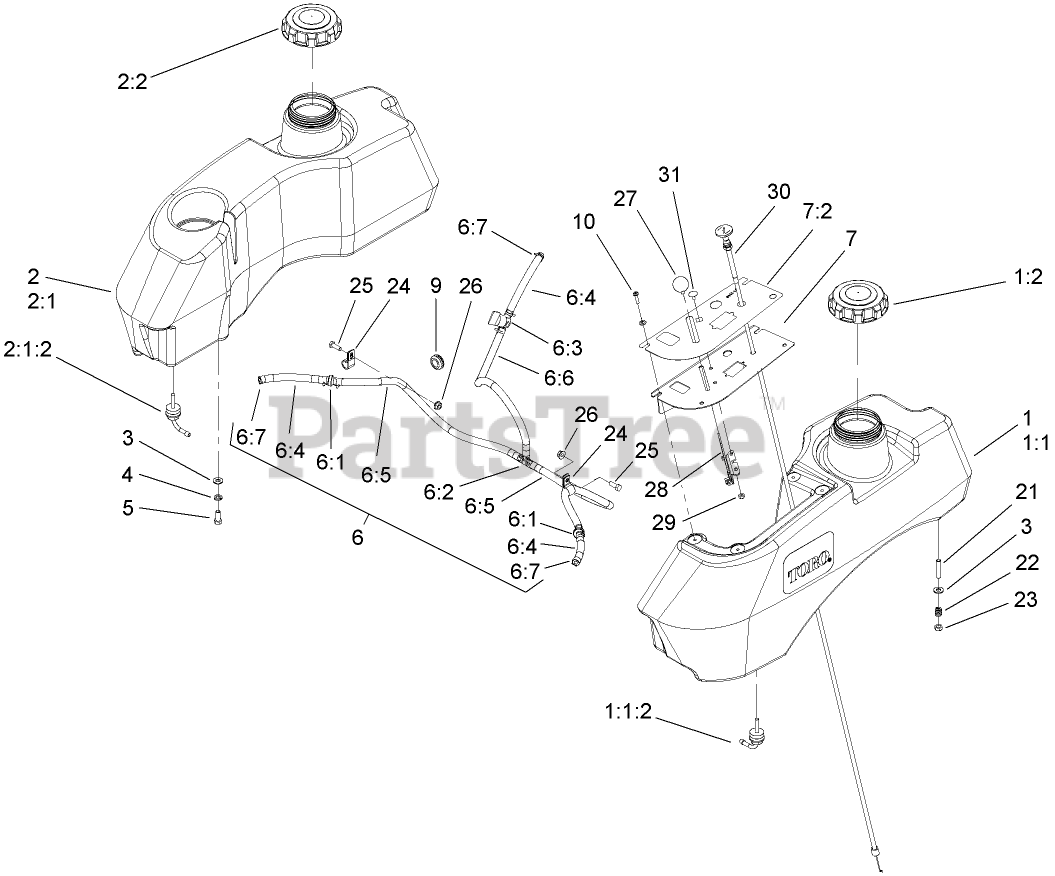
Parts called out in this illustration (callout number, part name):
1	LH FUEL TANK SERVICE KIT
1:1	LH FUEL TANK ASM
1:1:2	FITTING-FUEL, BULKHEAD
1:2	CAP-FUEL, GAS
2	RH FUEL TANK SERVICE KIT
2:1	RH FUEL TANK ASM
2:1:2	FITTING-FUEL, BULKHEAD
2:2	CAP-FUEL, GAS
3	WASHER-PLAIN
4	WASHER-LOCK
5	SCREW-HH
6	FUEL LINE ASM
6:1	VALVE-CHECK, FUEL
6:2	FITTING-TEE, BARBED
6:3	VALVE-FUEL
6:4	HOSE-FUEL
6:5	HOSE-FUEL
6:6	HOSE-FUEL
7	CONTROL PANEL ASM
7:2	DECAL-PANEL, CONTROL
9	GROMMET
10	SCREW-PPH
22	SPRING-TANK, FUEL
23	NUT-LOCK, NI
24	CLIP-LOOM
25	SCREW-HH
26	NUT-HF
27	KNOB-BALL
28	THROTTLE CABLE ASM
29	NUT-LOCK, NI
30	Control-Choke, Push / Pull
31	BOLT-CARR
